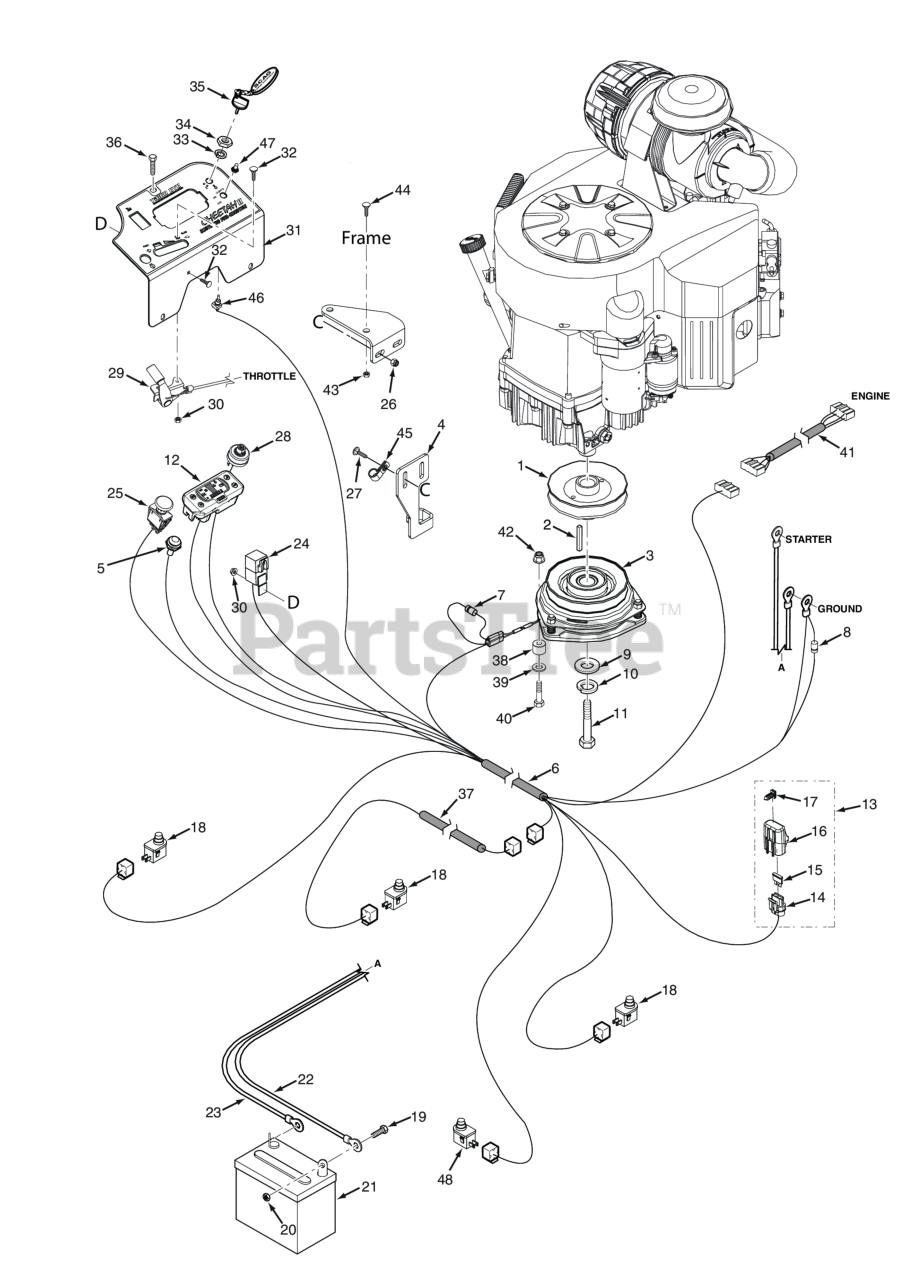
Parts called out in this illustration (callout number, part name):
1	Pulley, 5.80" Dia. - 1.125 Bore
2	Key, 1/4 x 1/4 x 3-1/4�
3	Electric Clutch w/Tag - GT-5 (ECV860, ECV940)
4	Bracket, Anti-Rotation
5	Indicator Light, Glow Plugs (Includes Mounting Hardware)
6	Wire Harness, SCZII-EFI
7	Diode, 600V 6 Amp
8	Decal, Forward Speed Selector
9	Flatwasher, 7/16-.469 x 1.75 x .25 (48, 52)
10	Lockwasher, 7/16� Spring
11	Bolt, Hex Head 7/16-20 x 2-1/4" w/Patch (Kawasaki)
12	Tiger Eye, Cluster Gauge
13	Single Fuse Assy., Excluding Fuse
14	Fuse Holder Assembly
15	FUSE, 20 AMP BLADE TYPE AUTOMOTIVE
16	Cover, Sealed Single
17	Clip, Fuse Holder
18	Switch, Interlock, Normally Open
19	Bolt, Hex Head 1/4-20 x .5" Battery, (Not Available Through Scag)
20	Nut, 1/4 - 20 Hex
21	Battery
22	Battery Cable, 18" Black (Kohler)
23	Battery Cable, 25" Red
24	Relay, 12V 40 AMP Standard
25	Switch, PTO - 10 Amp
26	Nut, Flange Head Elastic Stop 5/16-18
27	Bolt, Carriage 5/16-18x1" (large frame units only)
28	KEY SWITCH(INCLUDES MOUNTING HARDWARE)
29	Control Cable (Kawasaki FX921 Throttle & Choke Cable)
30	Nut, Elastic Stop #10-24
31	Instrument Panel w/Decal
32	Bolt, Carriage #10-24 x 1/2"
33	LOCK WASHER, 5/8" INTERNAL TOOTH
34	Nut, 5/8-32 Special
35	Key, Assembly w/Fob
36	CAP SCREW, 1/4-20 X 1/2" SERRATED FLANGE HEX
37	Wire Harness, Operator Platform -SCZ
38	Bushing, UHMW
39	Flatwasher, 5/16-.375 x .875 x .083 (35BV & 37BV-EFI)
40	Bolt, Hex Head 5/16-18 x 1-1/2" (Right Front Engine Mounting, Briggs and Kohler Only)
41	Wire Harness Adapter, Briggs & Stratton 37 BV-EFI
42	HEX NUT, ELASTIC STOP LOCK, 5/16-18
43	NUT, 3/8-16 SERRATED FLANGE HEX HEAD
44	Carriage Bolt, 3/8-16 x 1.0"
45	Clamp, Cable 1/2" I.D.
46	SWITCH, ON / OFF
47	BOOT, SWITCH
48	Switch, N/C
